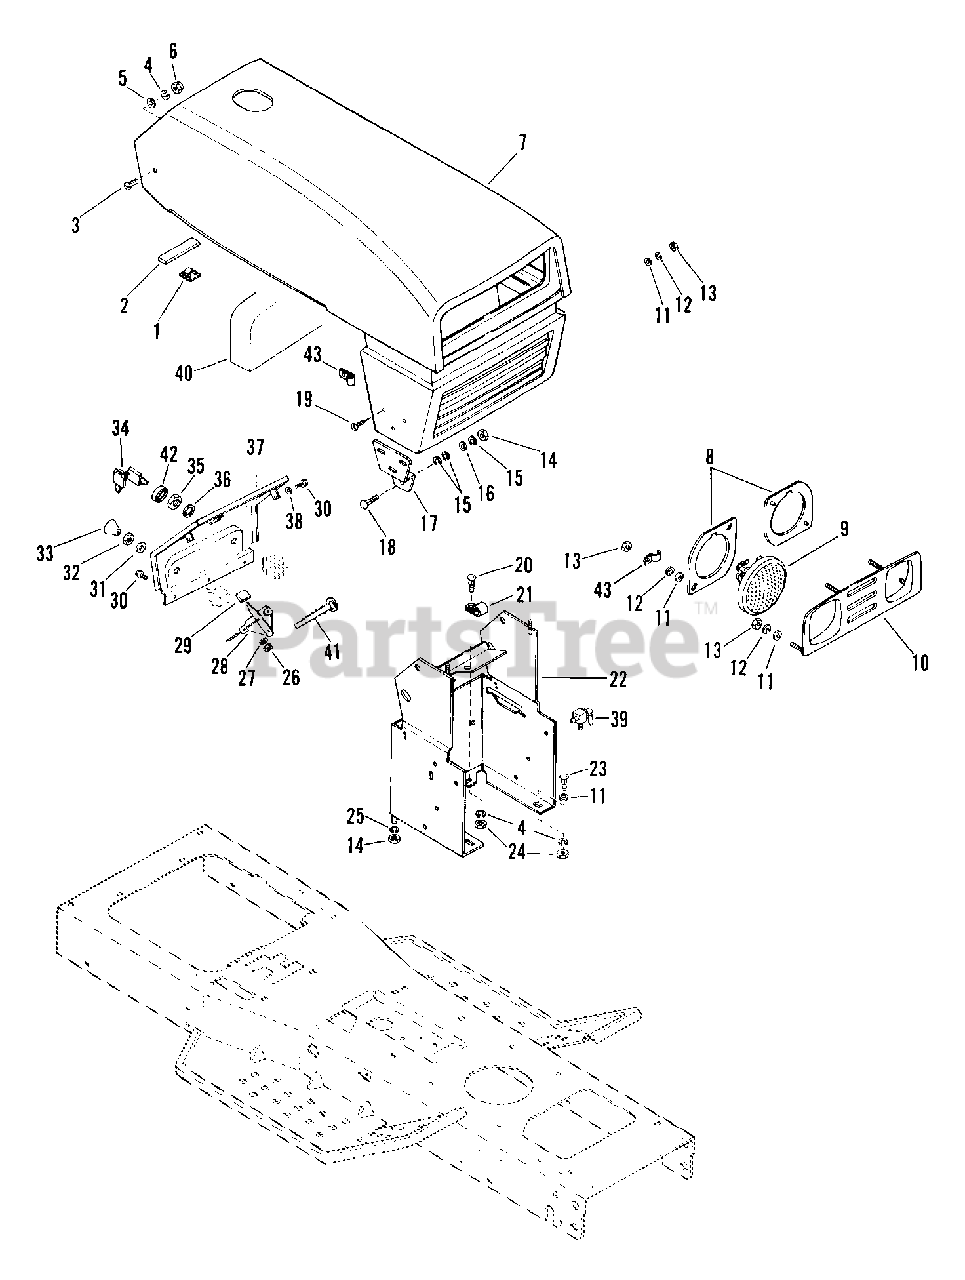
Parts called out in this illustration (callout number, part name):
1	WIRE CLIP
2	FOAM TAPE
3	SCR-MCH .31-18X.50 SLTR PL
4	WSHR-LK .312X.097 PL HVY
5	WSHR-FL-STL .38X.875X.083 PL
6	NUT-CROWN .312-18 PL
7	HOOD & GRILL
8	HEAD LIGHT RETAINER RING
9	HEAD LIGHT
10	HEADLIGHT INSERT
11	WSHR-FL-STL.312X.734X.065PL
12	WSHR-LK .250X.077 HVY PL
13	NUT-HEX .250-20 PL
14	NUT-HEX .375-16
15	WSHR-LK .375X.094 MED PL
16	WSHR-FL-STL .438X1.0X.083 PL
17	HOOD HINGE
18	BLT-RDHDSQSHNK .38-16X1.00 PL
19	SCR .25-20X.75 TS PH PL
20	BLT-HEX .31-18X.75 PL GR5
21	J-CLAMP
22	DASH BASE WITH DECALS
23	BLT-RDHDSQNK .31-18X.75 GR5 PL
24	NUT-HEX .312-18
25	WSHR-LK .375X.115 HVY PL
26	NUT-HEX 10-24 PL
27	WSHR-LK 10X.047 MED PL
28	THROTTLE CONTROL
30	SCR-SHT.MET10-16X.375 HWH PL B
31	WSHR-FL-STL .382X.812X.023 PL
32	NUT .50-20 PL
34	KEYS
35	NUT- PANEL .562-24 GRECO
36	WSHR-LK-INT .563X.040 PL
38	WSHR-FL-STL .250X.562X.049 PL
39	BALL VALVE
40	BAFFLE-HOOD
41	TIE DOWN
42	CAP - IGNITION SWITCH
43	J-CLIP
